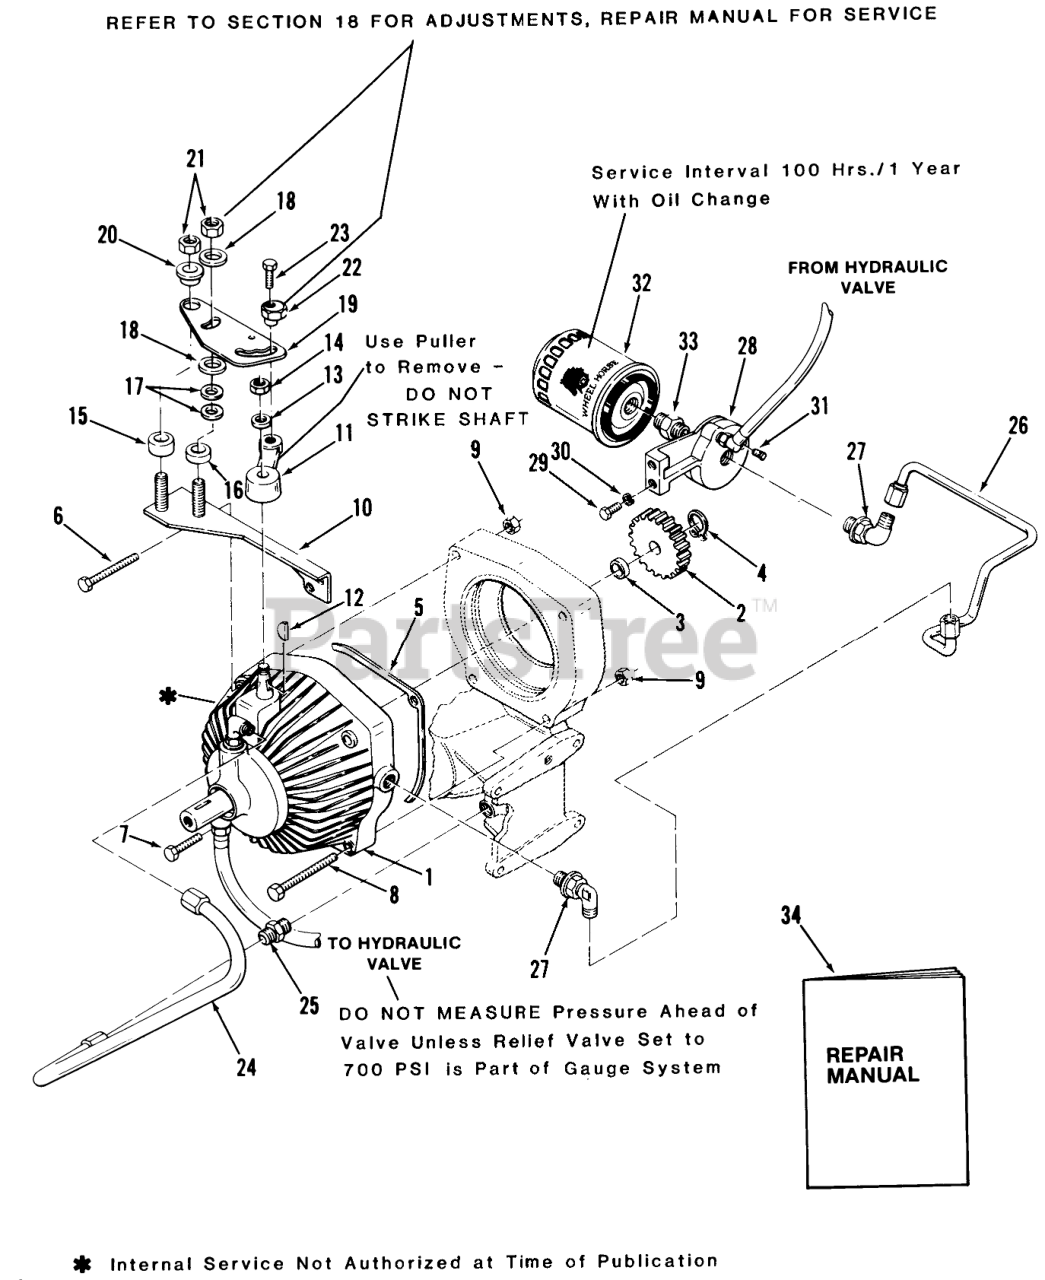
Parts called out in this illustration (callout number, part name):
1	Pump & Motor
2	GEAR 22T DRIVE
3	SPACER GEAR
4	SNAP RING- 5/8 EXT
5	GASKET
6	H H C S
7	Bolt
8	Bolt 3/8-16 x 6 1/2
9	Nut
10	ASSY-PLATE B
11	ARM-SPEED CONTROLB
12	Key #5 Woodruff
13	Washer
14	Eslok Nut
15	SPACER-PIVOT
16	SPACER-FRICTION
17	WASHER-SPRING DISC
18	FRICTION WASHER
19	CAM-SPEED CONTROL (NS)
20	CAM-SPACER
23	Bolt
24	ASSY-TUBE-SUCTION
25	FITTING-TUBE
26	ASM-TUBE FILTER OUTL
27	ELBOW
28	BASE-FILTER
29	Bolt
30	Lockwasher
31	PLUG 1/4 PIPE ALLEN
32	Filter-Oil
33	FITTING
34	Repair Manual
